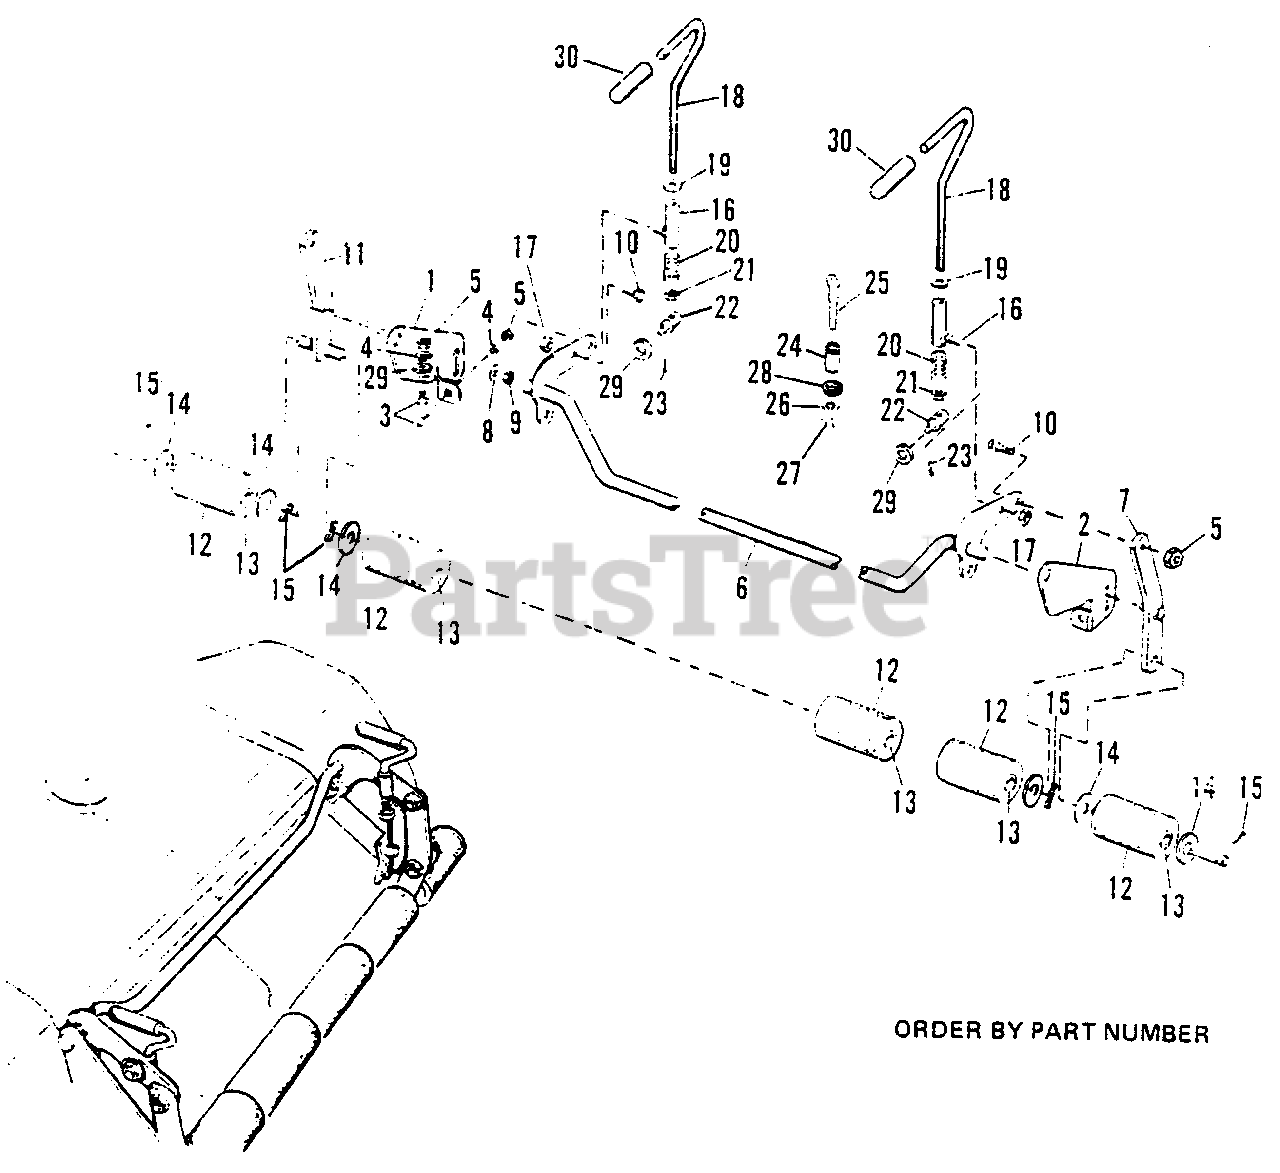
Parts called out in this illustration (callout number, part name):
1	Roller Bracket, R.H.
2	Roller Bracket, L.H.
3	Carriage Bolt, 3/8"-16 x 3/4"
4	Lockwasher, 3/8"
5	Full Hex Nut, 3/8"-16
6	Rocker Assembly Arm
7	Roller Bar Assembly, L.H.
8	Plain Washer, 3/8"
9	Full Hex Nut, 3/8"-16
10	Hex Capscrew, 3/8"-16 x 1"
11	Roller Shaft Assembly
12	Roller W/Bushing
15	Cotter Pin, 3/16"-1"
16	Socket Crank Assembly
17	Full Hex Nut, 3/16"-16
18	Adjusting Screw Assembly
19	Plain Washer, 3/8"
20	Adjusting Screw Spring
21	Hex Jam Nut, 3/8"-16
23	Cotter Pin, 3/32" x 3/4"
26	Lockwasher, 3/8"
27	Full Hex Nut, 3/8"-16 N.C.
28	Plain Flat Washer, 3/8"
29	Plain Washer, 5/16"
